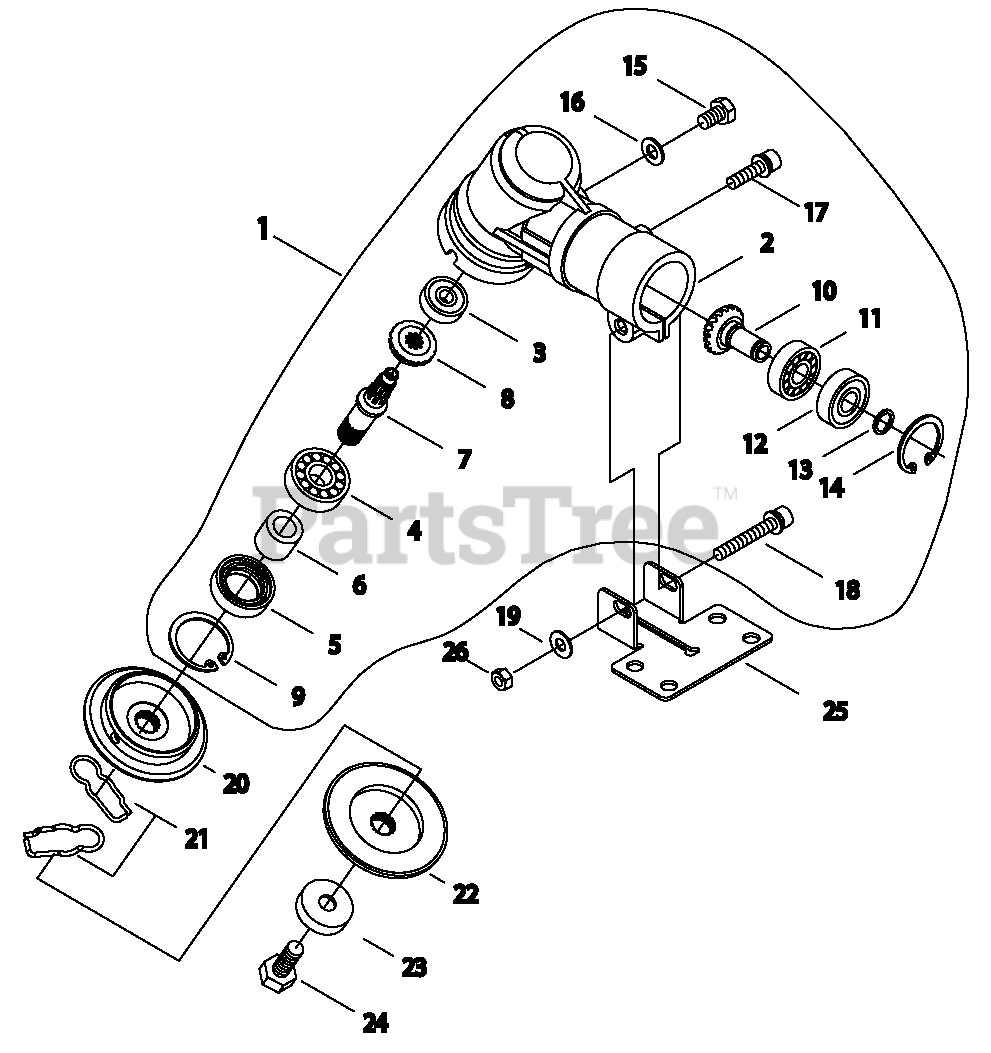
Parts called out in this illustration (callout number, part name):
1	GEAR CASE ASSY
2	HOUSING, GEAR CASE
3	BEARING, BALL 6000DDU
4	BEARING, BALL 6202
5	SEAL, OIL
6	COLLAR
7	SHAFT, GEAR
8	GEAR, BEVEL
9	RING, SNAP Ø35
10	PINION ASSY, BEVEL
11	BEARING, BALL 6001
12	BEARING, BALL 6001ZZ
13	RING, SNAP Ø12
14	RING, SNAP Ø28
15	BOLT M6×10
16	WASHER
17	BOLT M6×14
18	BOLT M6×40
19	WASHER
20	PLATE, ADAPTOR - UPPER
21	PIN, SLIDE
22	HOLDER
23	GUARD, BOLT
24	BOLT 10×37
25	CLAMP, LOWER
26	NUT, HEX M6
